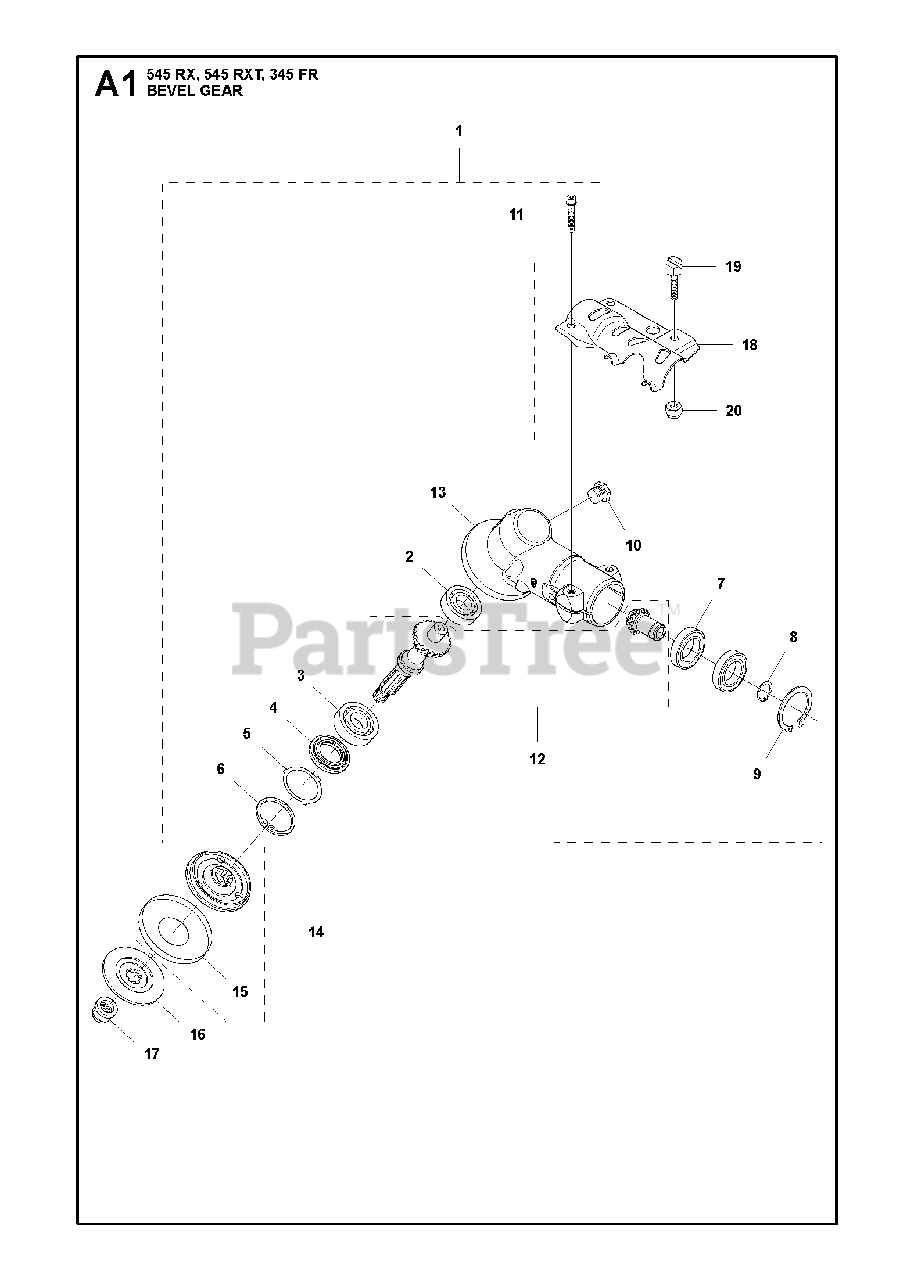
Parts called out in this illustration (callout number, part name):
2	BALL BEARING
3	BALL BEARING
4	SEAL
5	WASHER
6	RETAINING RING SGH 35
7	BALL BEARING
8	RETAINING RING SGA 15
9	RETAINING RING
10	PLUG
11	SCREW
12	SPARE PARTS KIT
13	GEAR HOUSING
15	RP TUBE INSERT
16	SUPPORT FLANGE
18	BRACKET
20	LOCKNUT M6
